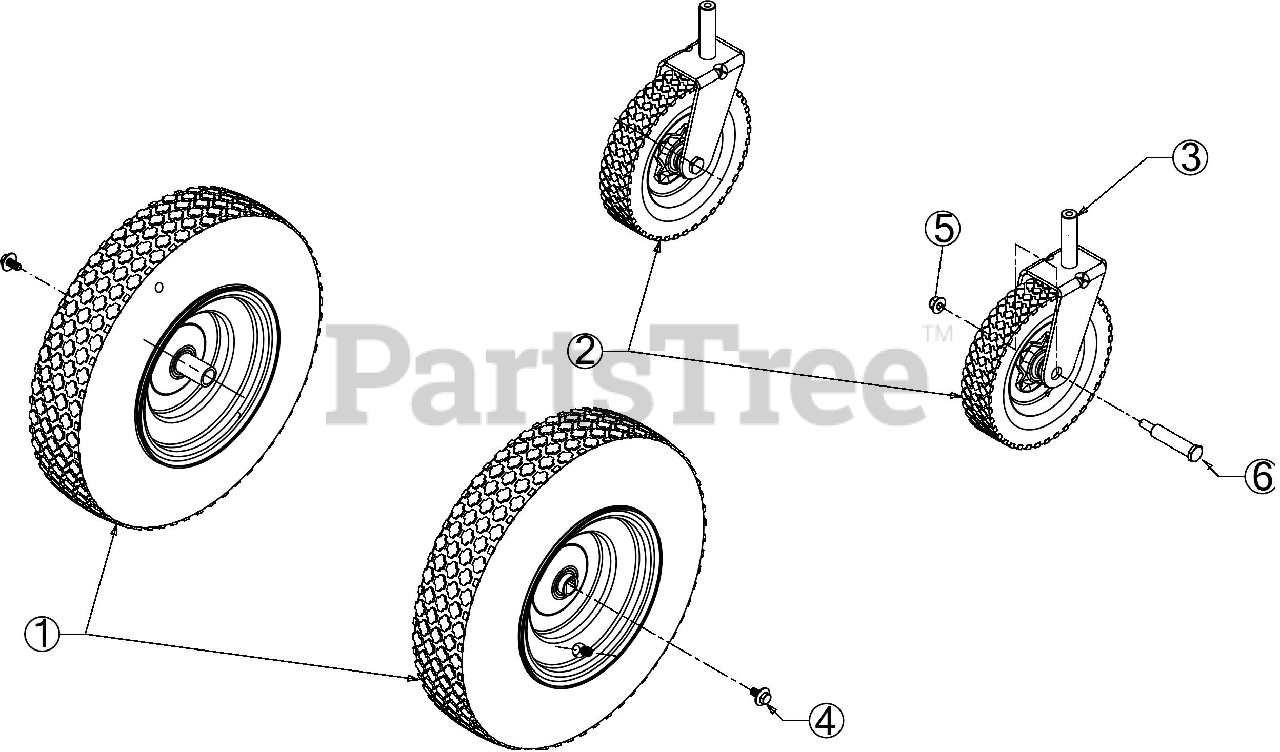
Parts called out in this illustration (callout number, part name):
1	WHEEL ASSEMBLY (16 x 4 x 8)
1	RIM ASSEMBLY (8.0X3.75) W/VALVE
1	RIM ASSEMBLY (8 x 3.75 x .75)
1	TUBELESS VALVE
1	TIRE 4.80 x 8
2	FLANGE BUSHING
2	CASTER WHEEL
3	CASTER WHEEL YOKE
4	SCREW 5/16-24 x .750 GR5
6	SHOULDER SCREW:.625 x 2.515 x 1.00
